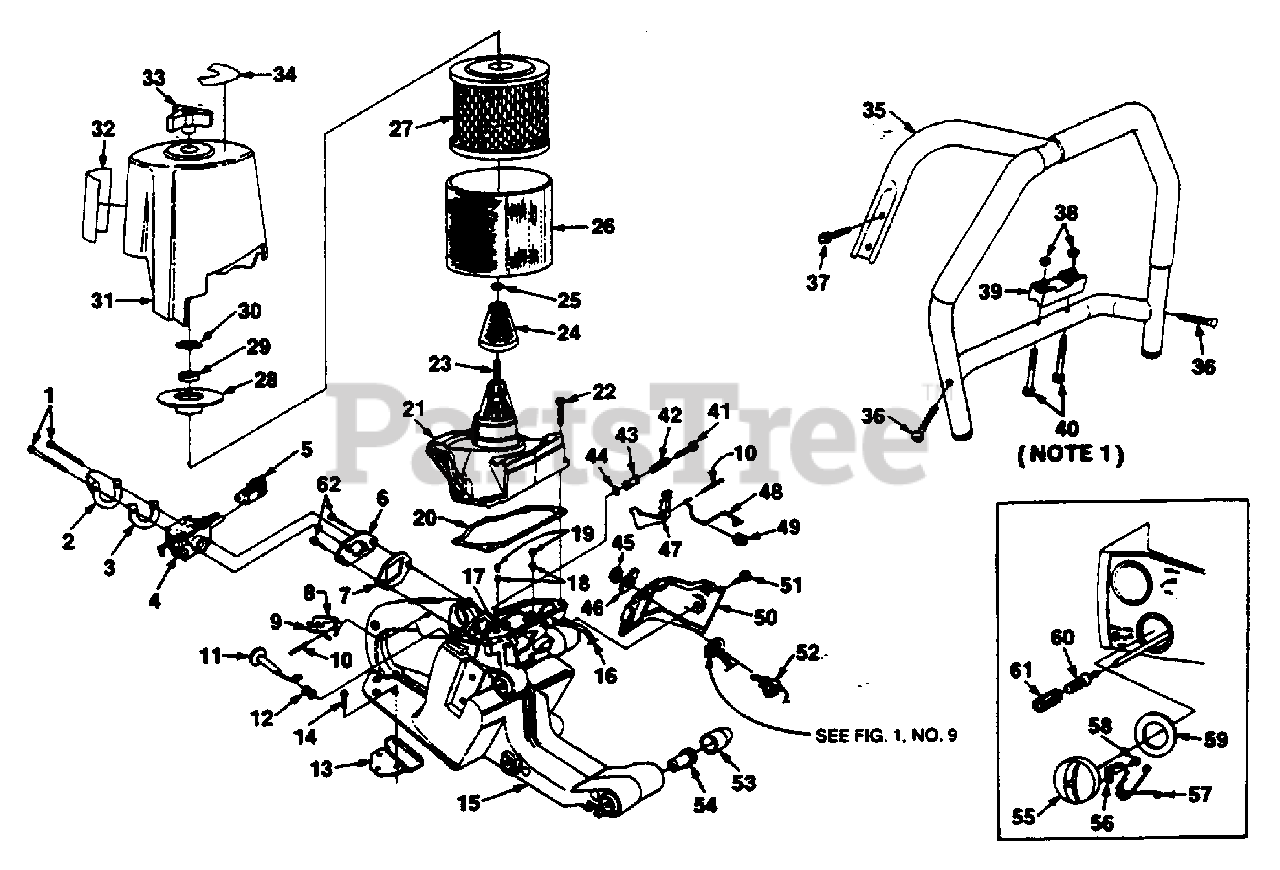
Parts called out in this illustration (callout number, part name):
1	SCREW- Socket Hd.
2	SHIELD- Carburetor
3	GASKET- Carburetor shield
4	CARBURETOR- (Walbro WJ-2)
5	GROMMET
6	ADAPTOR- Carburetor
7	GASKET- Carburetor
8	LOCK- Trigger
9	SPRING- Flat
10	PIN- Trigger
11	ROD- Choke
12	GROMMET
13	PLATE- Wear
14	SCREW- (8-32 x 3/8")
15	HOUSING- Engine
16	TUBING- Rubber (5 3/4") (Pulse Line)
17	TUBING- Rubber (5 3/4") (Fuel Line)
18	VALVE- Check
19	FILTER
20	GASKET
21	COVER- Carburetor chamber
22	SCREW- Pan hd. (8-32 x 5/8")
23	BOLT
24	PREFILTER
25	"O" RING
26	FOAM- Air filter
27	ELEMENT- Air filter
28	COVER- Filter element
29	NUT- Hex (5/16-18)
30	RING- Retaining
31	COVER- Filter
32	DECAL- Warning
33	KNOB
35	HANDLE BAR
36	SCREW- Mach. hd. (10-24 x 11/2")
37	SCREW- Oval hd.
38	NUT- Locking (1/4-28")
39	BRACKET- Handle bar
40	SCREW- Mach Oval hd. (1/4-20 x 1/2")
41	PIN-Throttle lock
42	SPRING- Compression
43	BUSHING
44	RING- Retaining
45	NUT- Hex
46	PLATE- Indicating
47	TRIGGER- Throttle
48	ROD- Throttle
49	GROMMET
50	COVER- Switch
51	SCREW- Pan washer (8-32 x 1/2")
52	SWITCH- Toggle
53	ISOLATOR- Vibration
54	SLEEVE- Flanged
55	CAP- Fuel
56	BEAD- Chain
57	KEEPER- Cap
58	SCREW- Thread Forming (#6 x 1/4")
59	GASKET- Cap
60	FILTER- Fuel
61	ELEMENT- Filter
62	SCREW- Hex sems (10-24 x 3/4")
